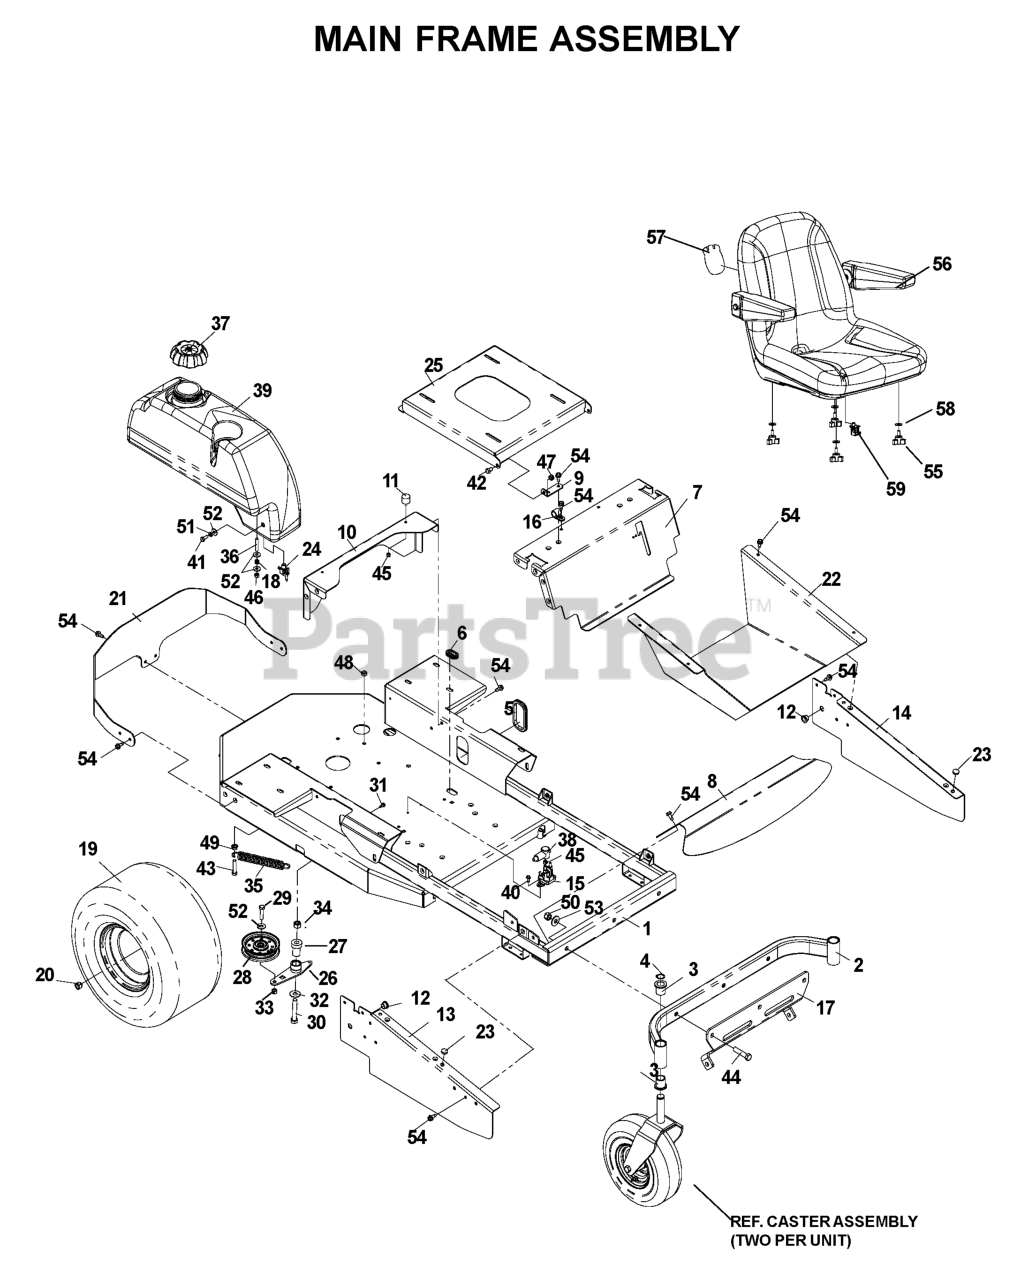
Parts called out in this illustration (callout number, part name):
1	MAINFRAME W/DECALS
2	CASTER AXLE W/BUSHING
3	BUSHING, FLANGED
4	RETAINING RING, 7/8"
6	RUBBER GROMMET
7	SEAT SUPPORT W/DECALS
8	FRONT FOOT PLATE
9	SEAT BRACKET-BLACK
10	REAR SUPPORT-ORANGE
11	STUD/PLATE MOUNT
12	BUSHING, FLANGED NYLON
13	RH FRAME SIDE-ORANGE
14	LH FRAME SIDE-ORANGE
17	STRUT MOUNT
19	TIRE ASSY
20	LUG NUT 1/2F
21	REAR BUMPER-BLACK
22	FLOOR PAN-ORANGE
23	GROMMET, BUMPER
24	FUEL VALVE
25	SEAT SUPPORT W/DECALS
26	PUMP IDLER ARM WELDMENT
27	IDLER SPINDLE
28	FLAT IDLER PULLEY
29	HCS 3/8C X 1 1/2
30	HCS 1/2C X 2 3/4
31	SCREW #10 X 1/2 SELF TAPPING
32	WASHER 1/2 FLAT
33	NUT 3/8C CENTERBLOCK
34	NUT 1/2-13 HEX NYLOC ZD
36	STUD, 5/16C
37	FUEL CAP
39	LEFT TANK W/CUP HOLDER
40	SCREW 1/4 X 5/8
41	HCS 5/16C X 3/4
42	BOLT .375 X .5
43	HCS 3/8C X 2 1/4
44	HEX SCREW-.5C X 2.25
45	NUT.1/4-20.HEX.NYLOC.ZD
46	NUT 5/16 NYLOC
47	NUT 3/8C CENTERBLOCK
48	NUT 3/8-16 NYLOC
49	NUT 3/8C WHIZ
50	NUT 1/2-13 HEX NYLOC ZD
51	WASHER.LOCK.HVY.HLCL.SPR.5/16
52	WASHER 5/16 FLAT
53	WASHER 1/2 FLAT
54	BOLT 5/16-18 X 3/4
55	KNOB W/STUD
56	SEAT W/ARMRESTS
57	DECAL, CROWN H
58	WASHER 5/16 FLAT
59	SEAT SWITCH
539108008	RIM.8"X6.38".ZTR
539108009	TIRE 18 X 9.5-8 4 PLY
539912234	VALVE STEM TR-412
